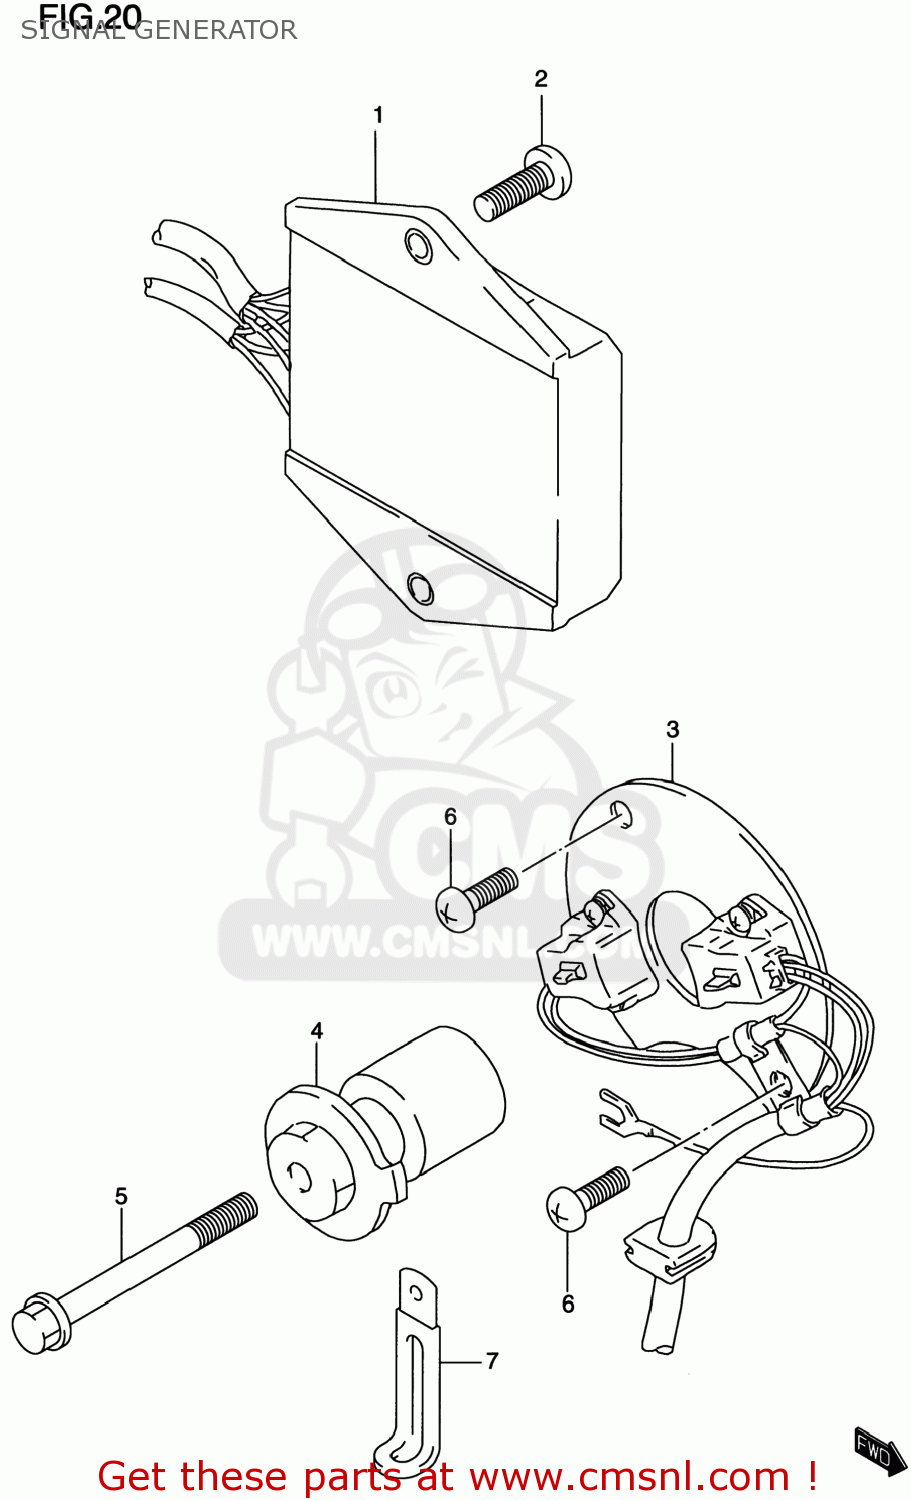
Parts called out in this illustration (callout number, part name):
1	IGNITOR ASSY
2	SCREW
3	SIGNAL GENERATOR ASSY
4	ROTOR,SIGNAL
5	BOLT(6X60)
6	SCREW
7	CLAMP(L:45)
